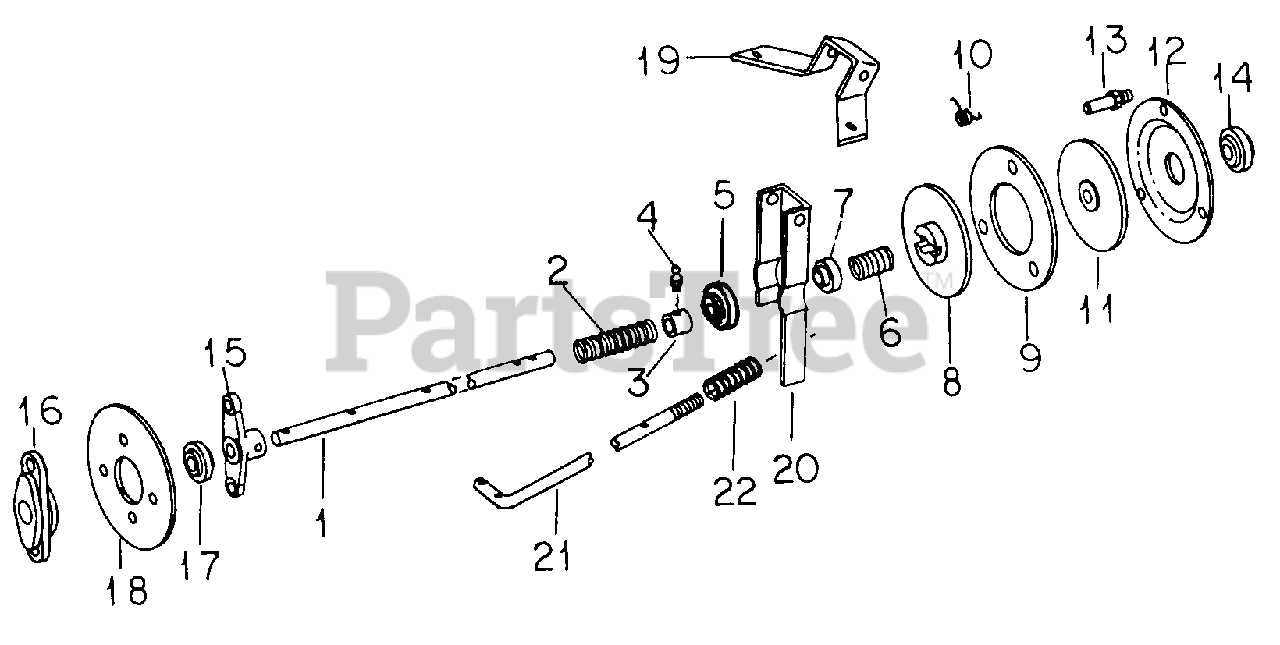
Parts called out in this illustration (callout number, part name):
1	Shaft w/Tag, Clutch
2	Spring, Loading
3	Bushing
4	Fitting, 1/4 Lub
5	Bearing, Throwout
6	Spring, Teasing
7	Spacer, Spring
8	Hub Assy, Pressure Plate OR
9	Disc, Clutch Friction
10	Spring, Driving Disc
11	Hub Assy, Pressure Plate Locating OR
12	Disc, Clutch Driving
13	Stud, Drive
14	Bushing, Ball
15	Arm, Coupling
16	Coupler, Driveshaft
17	Bushing, Ball
18	Disc, Flex Coupling
19	Hanger, Clutch Lever
21	Rod, Clutch Release
22	Spring, Release Rod
